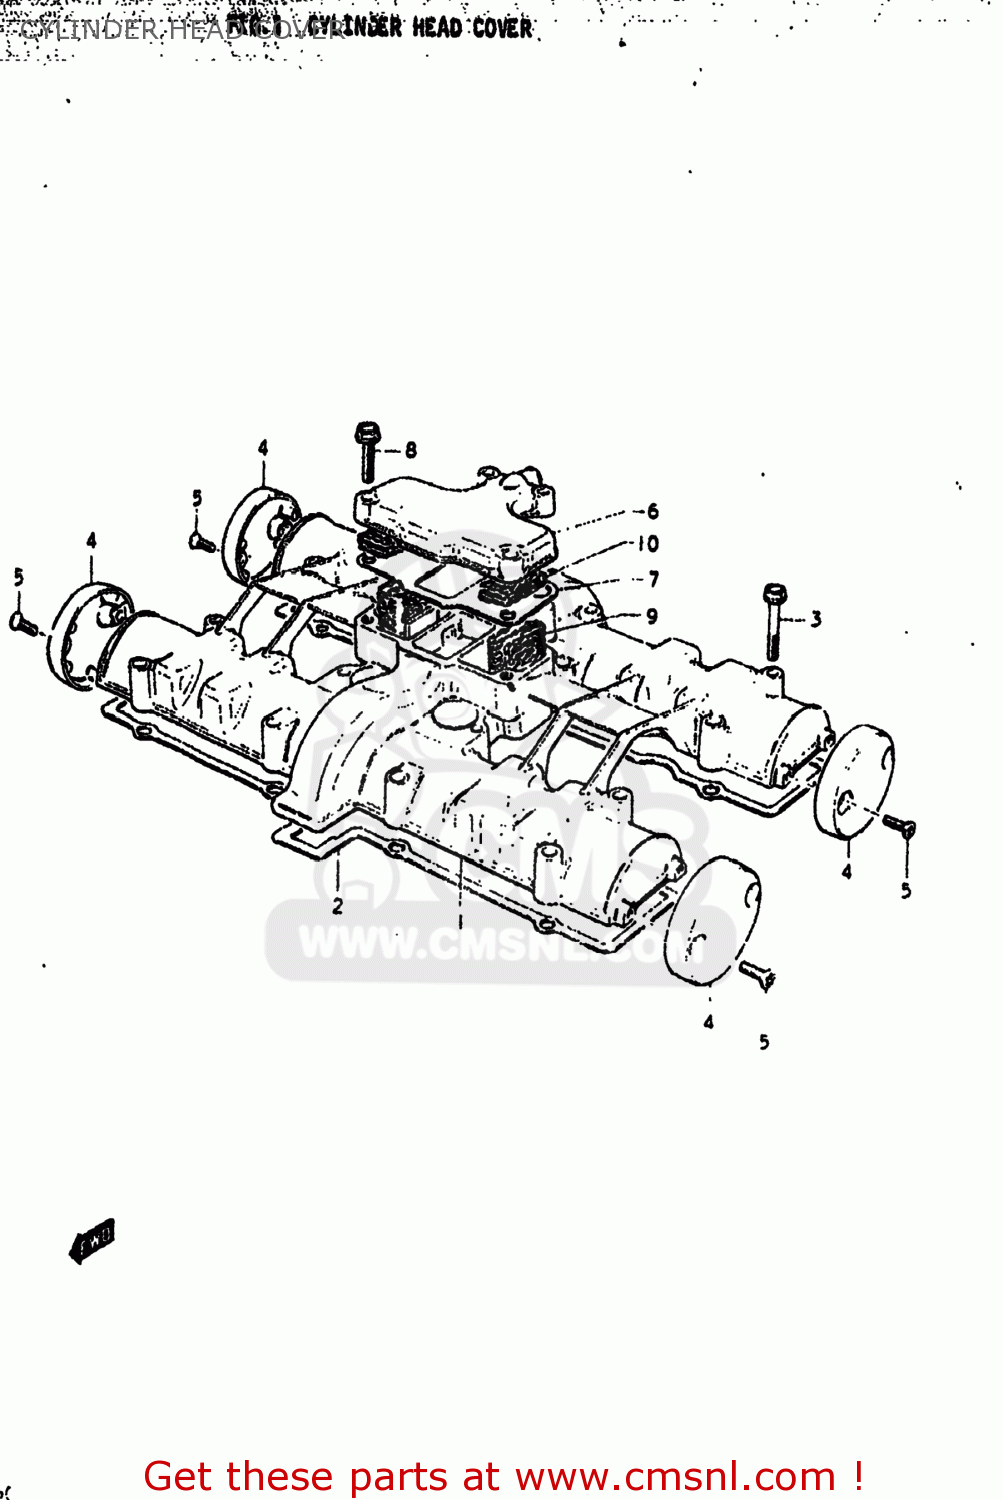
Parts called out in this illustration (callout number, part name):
1	COVER,CYLINDER HEAD
2	GASKET,CYLINDER HEAD COVER (MCA)
3	BOLT
4	CAP,CYLINDER HEAD COVER
5	SCREW
6	COVER,BREATHER
7	GASKET (MCA)
8	BOLT
9	COVER,BREATHER
10	SEPARATOR,OIL BREATHER
